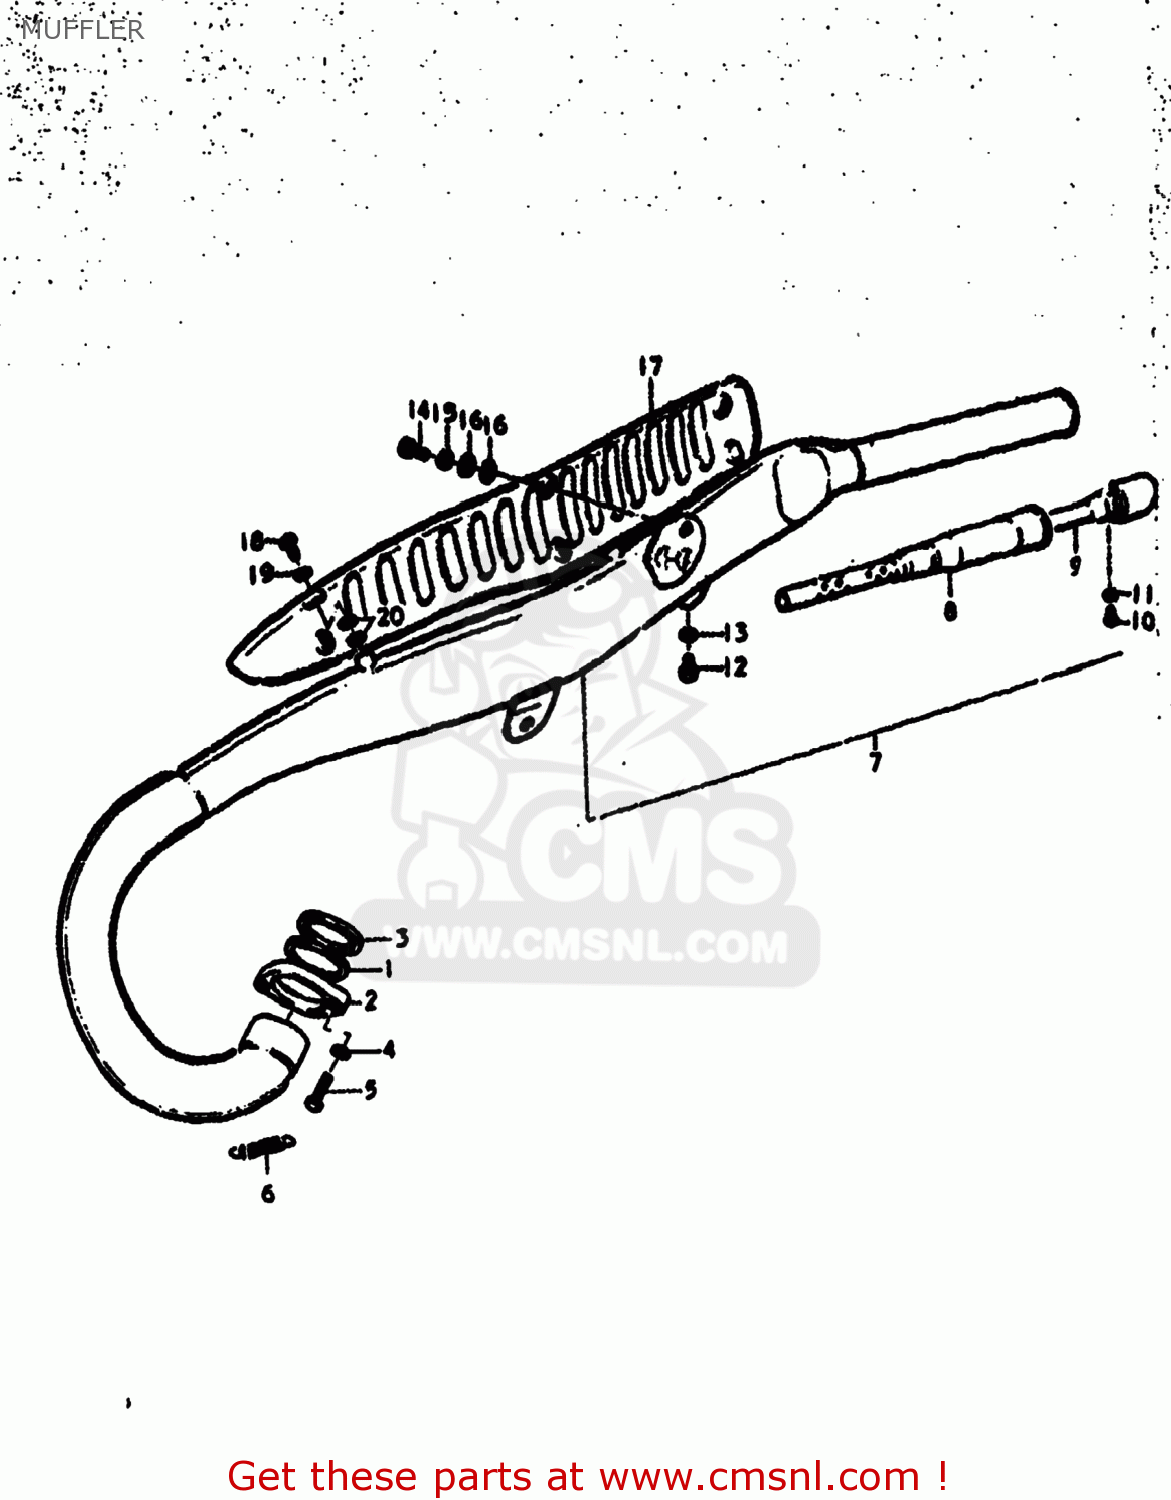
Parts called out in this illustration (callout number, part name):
1	GASKET,EXHAUST PIPE (NAS)
2	CLAMP,EXHAUST PIPE
3	CUSHION,EXHAUST PIPE
4	LOCK WASHER
5	BOLT
6	SPRING
7	MUFFLER ASSEMBLY
8	ARRESTER,SPARK
9	TUBE,MUFFLER CLEAN OUT
10	SCREW(6X8)
11	LOCK WASHER
12	BOLT 10X9
13	GASKET(10X14X3.6) (NAS)
14	BOLT 10X20
15	LOCK WASHER
16	WASHER
17	COVER,MUFFLER
18	SCREW
19	WASHER
20	GASKET 6.2X12X1.5 (MCA)
